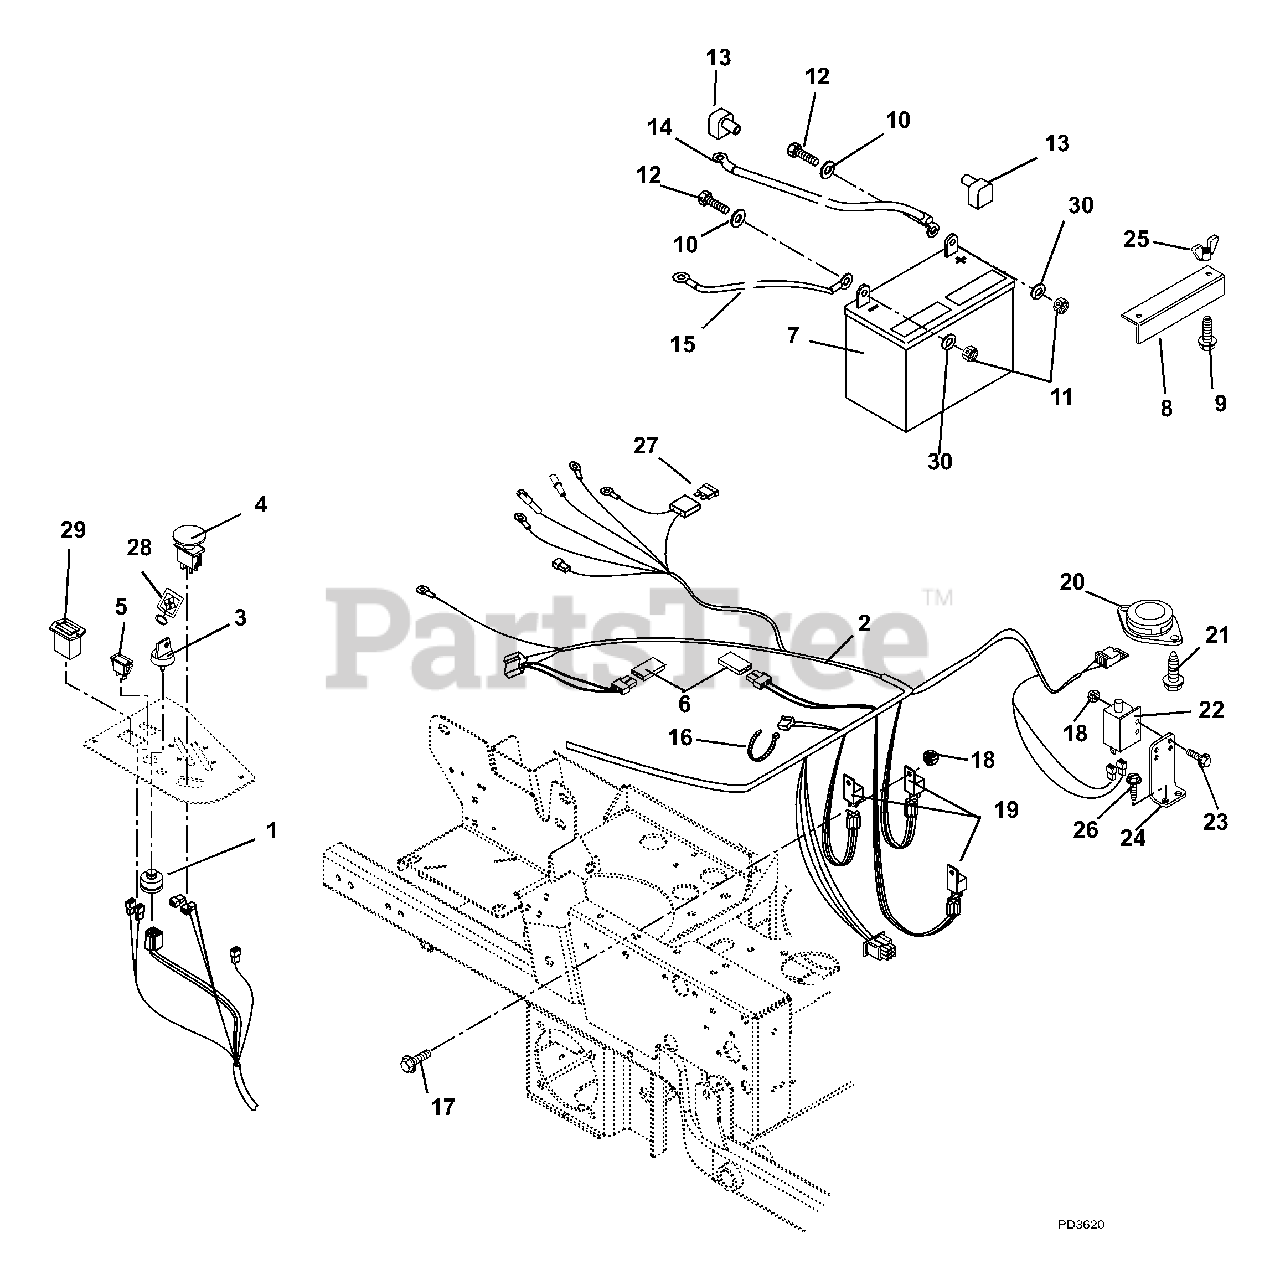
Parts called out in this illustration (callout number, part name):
1	Key Switch
2	Harness, IZ/CZ
3	Key with Shield
4	Switch, Clutch With Retainer Ring
5	Light, Indicator
6	Diode, Connector Shell
8	Hold Down
9	Bolt, Round Head Square Neck .25-20 x 7.50
10	Washer, Flat Steel .281 x .620 x .065
11	Nut, Locking Top Flange .25-20
12	Bolt, Hex .25-20 x .75 Grade 5
13	Insulator
14	Cable, Positive, 26 inch
15	Cable, Negative Battery
16	Cable Tie
17	Screw, Machine 10-24 x .50 Hex Washer Head
18	Nut, Locking Nylon 10-24 With Insert
19	Relay, Sealed with diode
20	Seat Switch
21	Screw, Tapping 12-24 x .50 Hex Washer Head
22	Switch, Double Pole N.O./N.O.
23	Screw, Machine 10-24 x .75 Hex Washer Head
24	Mount, Brake Switch
25	Nut, Locking Wing .25-20
26	Screw, Tapping .25-20 x .50 Hex Washer Head
27	Fuse, 30 Amp
28	Key Chain
29	Hour Meter
30	Washer, Locking .25 x .062 Regular
